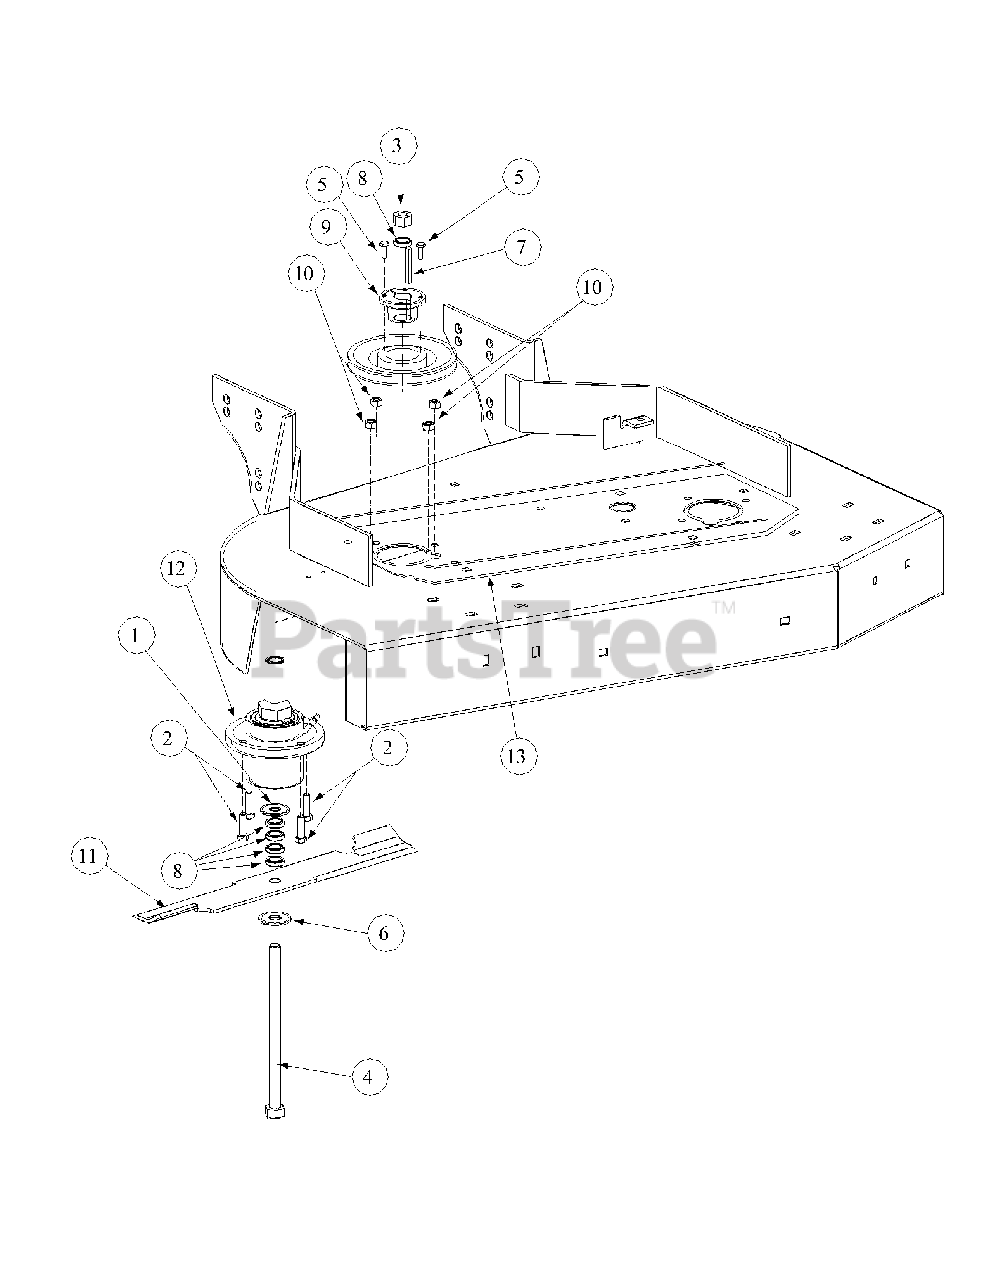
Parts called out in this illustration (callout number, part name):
1	Flat Washer, 1-1/2 x 5/8 x .05
2	Hex Cap Screw, 3/8-16 x 1-1/4
3	Hex Nut, 5/8-11
4	Hex Cap Screw, 5/8-11 x 9-1/2
5	Hex Cap Screw, 1/4-20, .75
6	Flat Washer, 5/8 Zinc
7	Key Stock, 1/4 x 1/4 x 2
8	Blade Spacer, 5/8 ID, 1/4 Thick
10	Lock Nut, 3/8-16
11	Blade 18"
12	Spindle Assembly
13	Deck Stiffener
